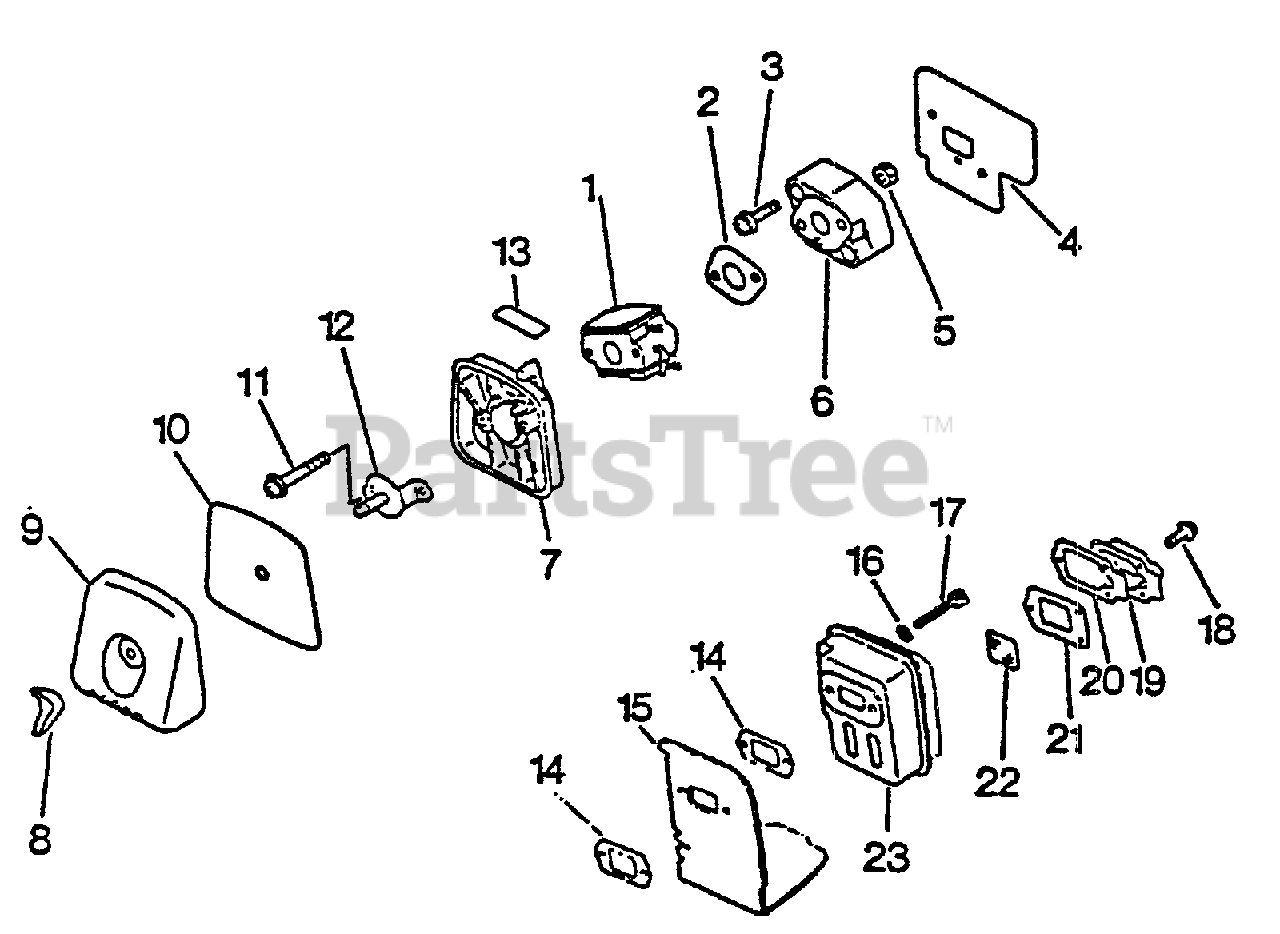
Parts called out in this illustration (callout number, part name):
1	CARBURETOR - C1U-K14
2	GASKET, INTAKE
3	SCREW 5×22
4	GASKET, INTAKE
5	NUT M5
6	INSULATOR, INTAKE
7	CASE, AIR FILTER
8	WINGNUT - 6
9	COVER, AIR FILTER
10	FILTER, AIR
11	SCREW 5×64
12	PLATE, PREVENT
13	LABEL - CHOKE
14	GASKET, EXHAUST
15	COVER, MUFFLER
16	WASHER, FLAT 5.5×10×0.8
17	BOLT 5×55
18	SCREW 4×10
19	GUIDE, EXHAUST - INNER
20	GUIDE, EXHAUST
21	GASKET, EXHAUST
22	SCREEN, SPARK ARRESTER
